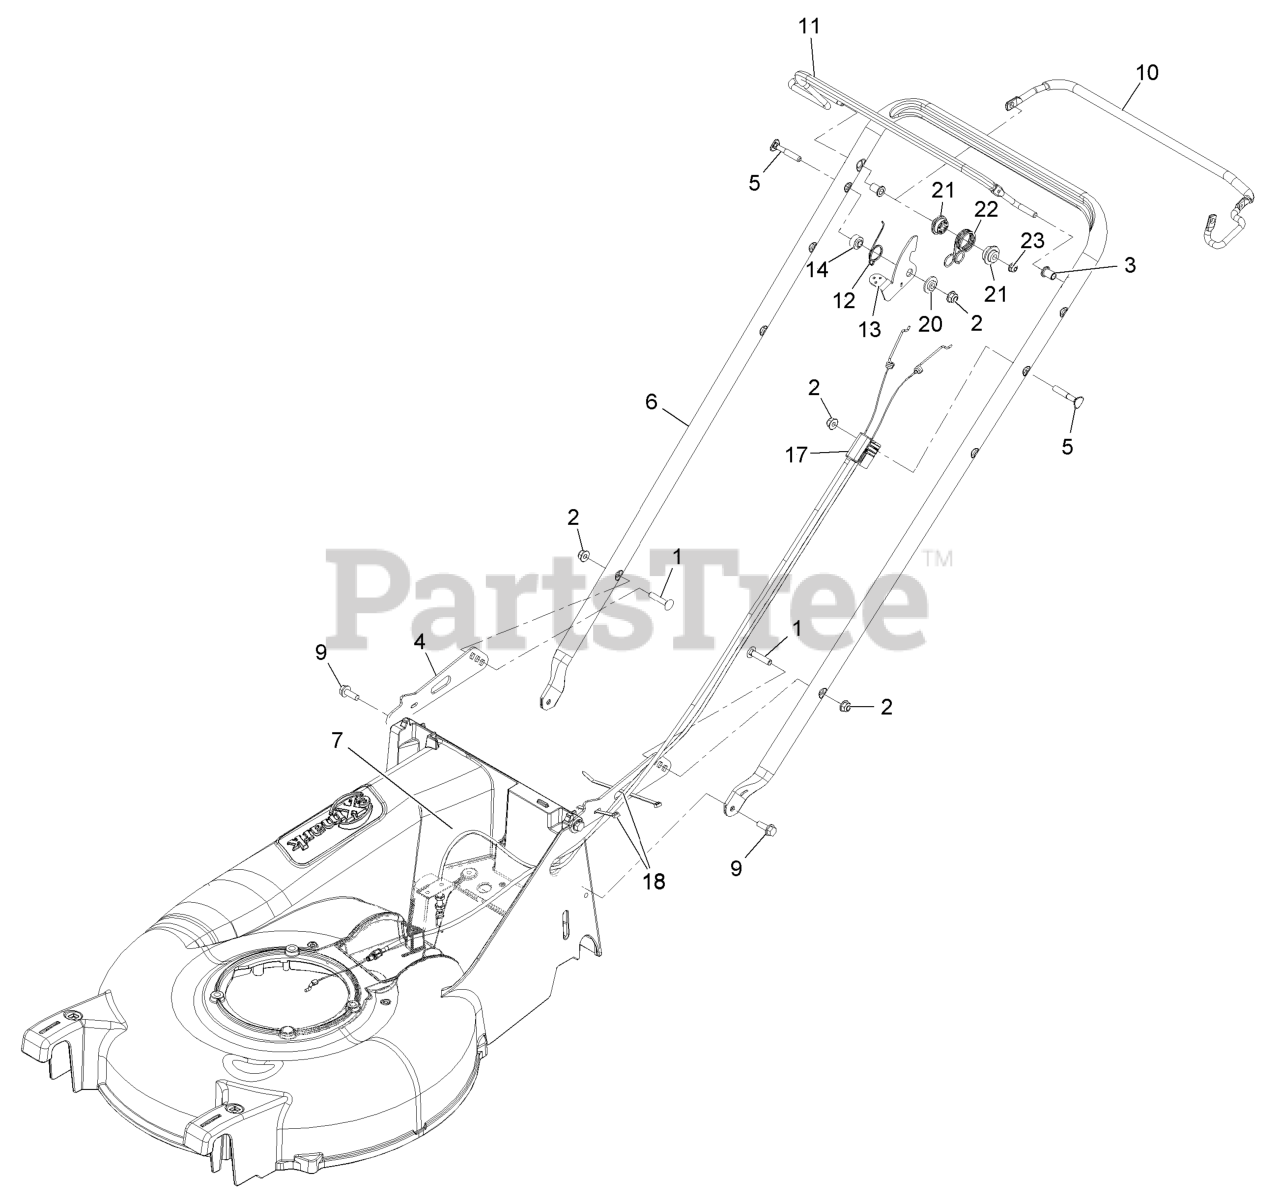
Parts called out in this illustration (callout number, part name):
1	BOLT-CARR
2	NUT-HF, NI
3	BUSHING-HANDLEBAR
4	BRACKET,HANDLEBAR
6	HANDLEBAR-P21
7	CABLE, DRIVE EC21
9	SCREW-TAPTITE
10	BAIL-DRIVE COATED
12	SPRING-LEVER, BBC
13	LEVER-BBC
14	BUSHING-STEPPED
17	CABLE-BBC
18	TIE-CABLE
20	WASHER-STEPPED
21	BUSHING-SPRING, PIVOT
22	SPRING,BBC RETURN
